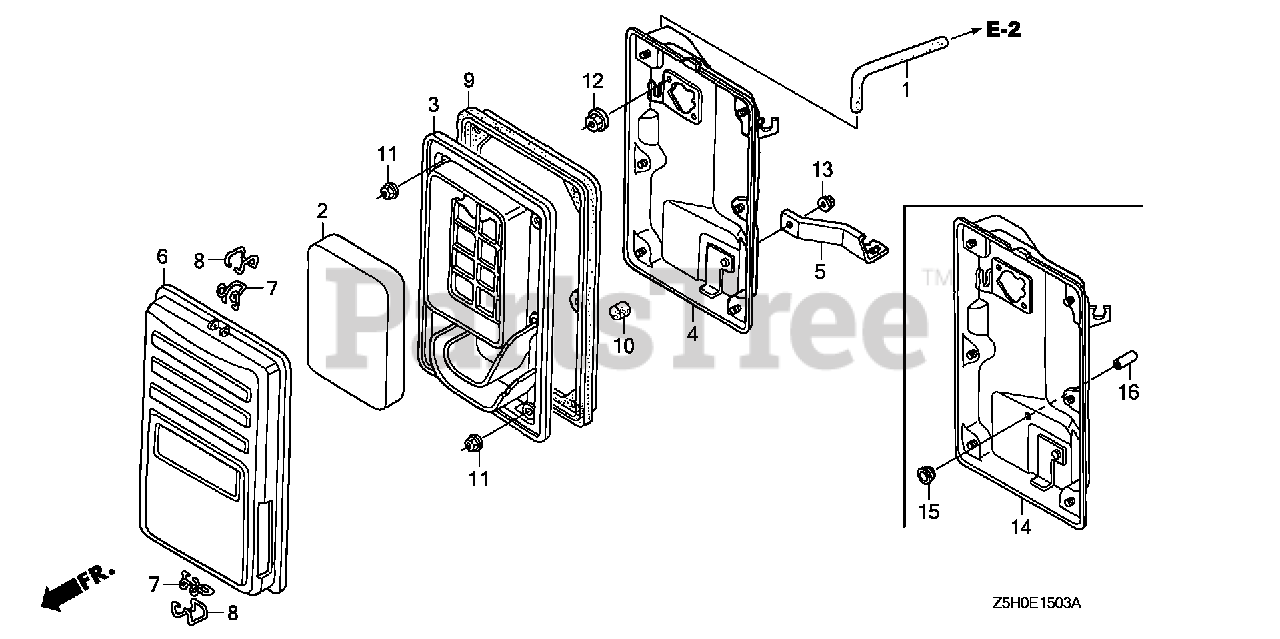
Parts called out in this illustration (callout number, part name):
1	TUBE, BREATHER
2	ELEMENT, AIR CLEANER
3	SEPARATOR, AIR CLEANER
4	HOUSING, AIR CLEANER
5	STAY, AIR CLEANER
6	COVER, AIR CLEANER
7	CLIP A, AIR CLEANER WIRE
8	CLIP B, AIR CLEANER WIRE
9	SEAL, AIR CLEANER
10	FILTER, DRAIN TUBE
11	NUT, FLANGE (5MM)
12	NUT, FLANGE (6MM)
13	NUT, FLANGE (6MM)
14	HOUSING, AIR CLEANER
15	GROMMET, AIR CLEANER
16	CAP, SEALING
